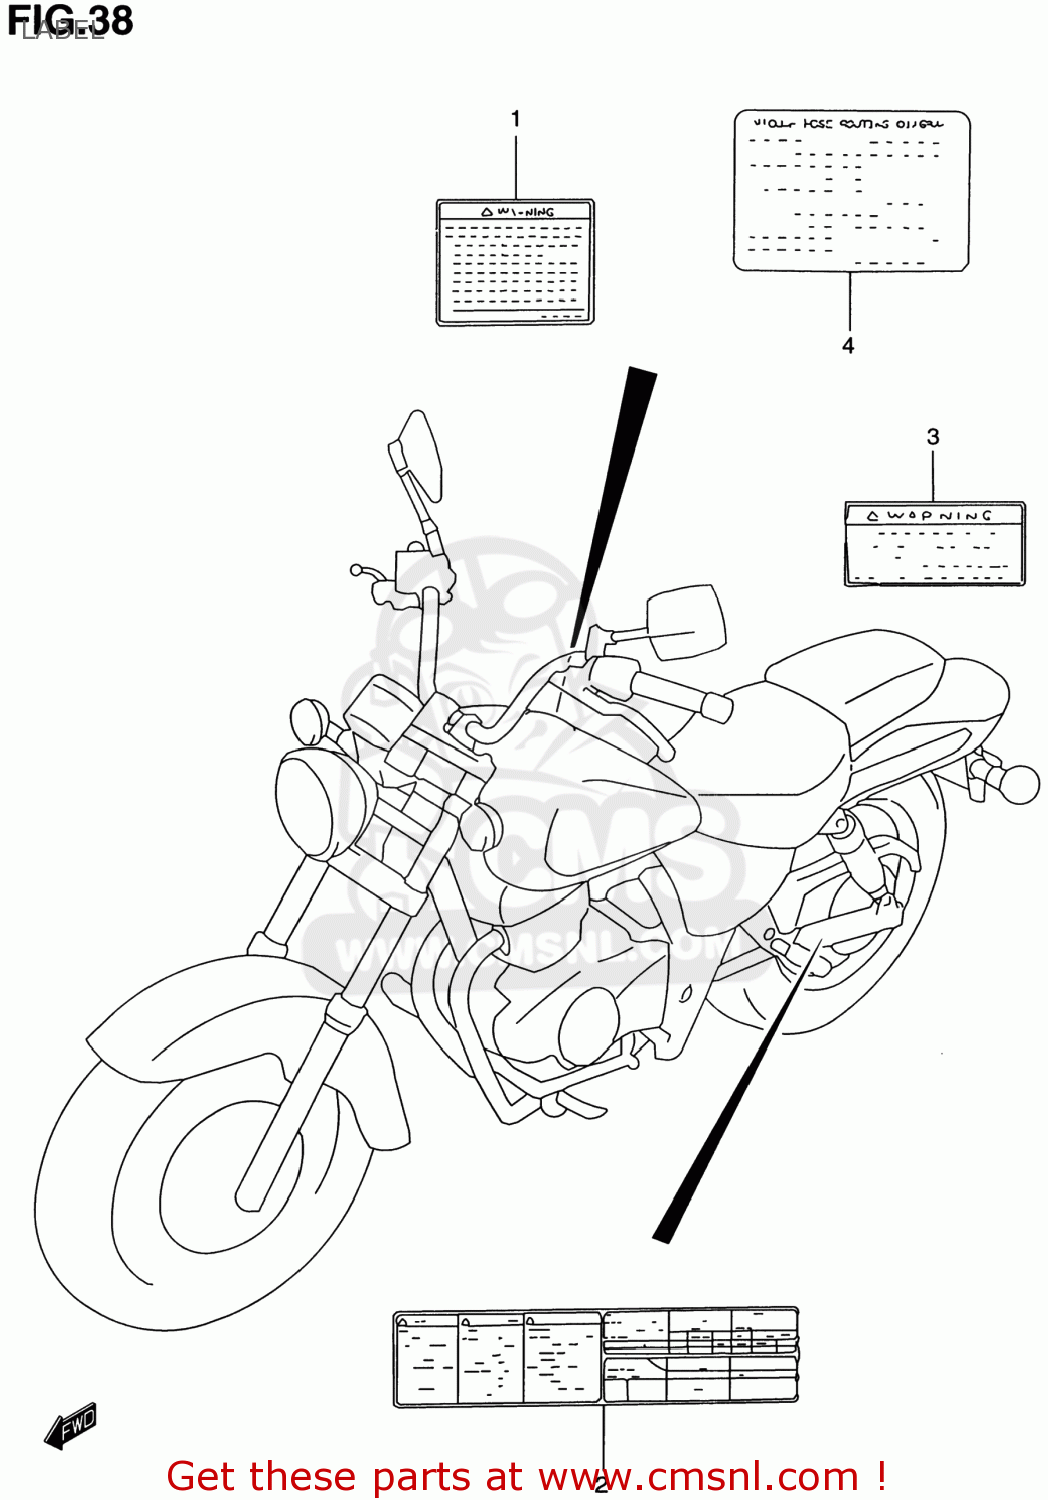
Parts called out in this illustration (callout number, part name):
1	LABEL,GENERAL WARNING
2	LABEL,TIRE INFORMATION
3	LABEL (MANUAL NOTICE)
4	LABEL,VACUUM HOSE ROUTING
5	MANUAL,OWNER'S GZ250Y
